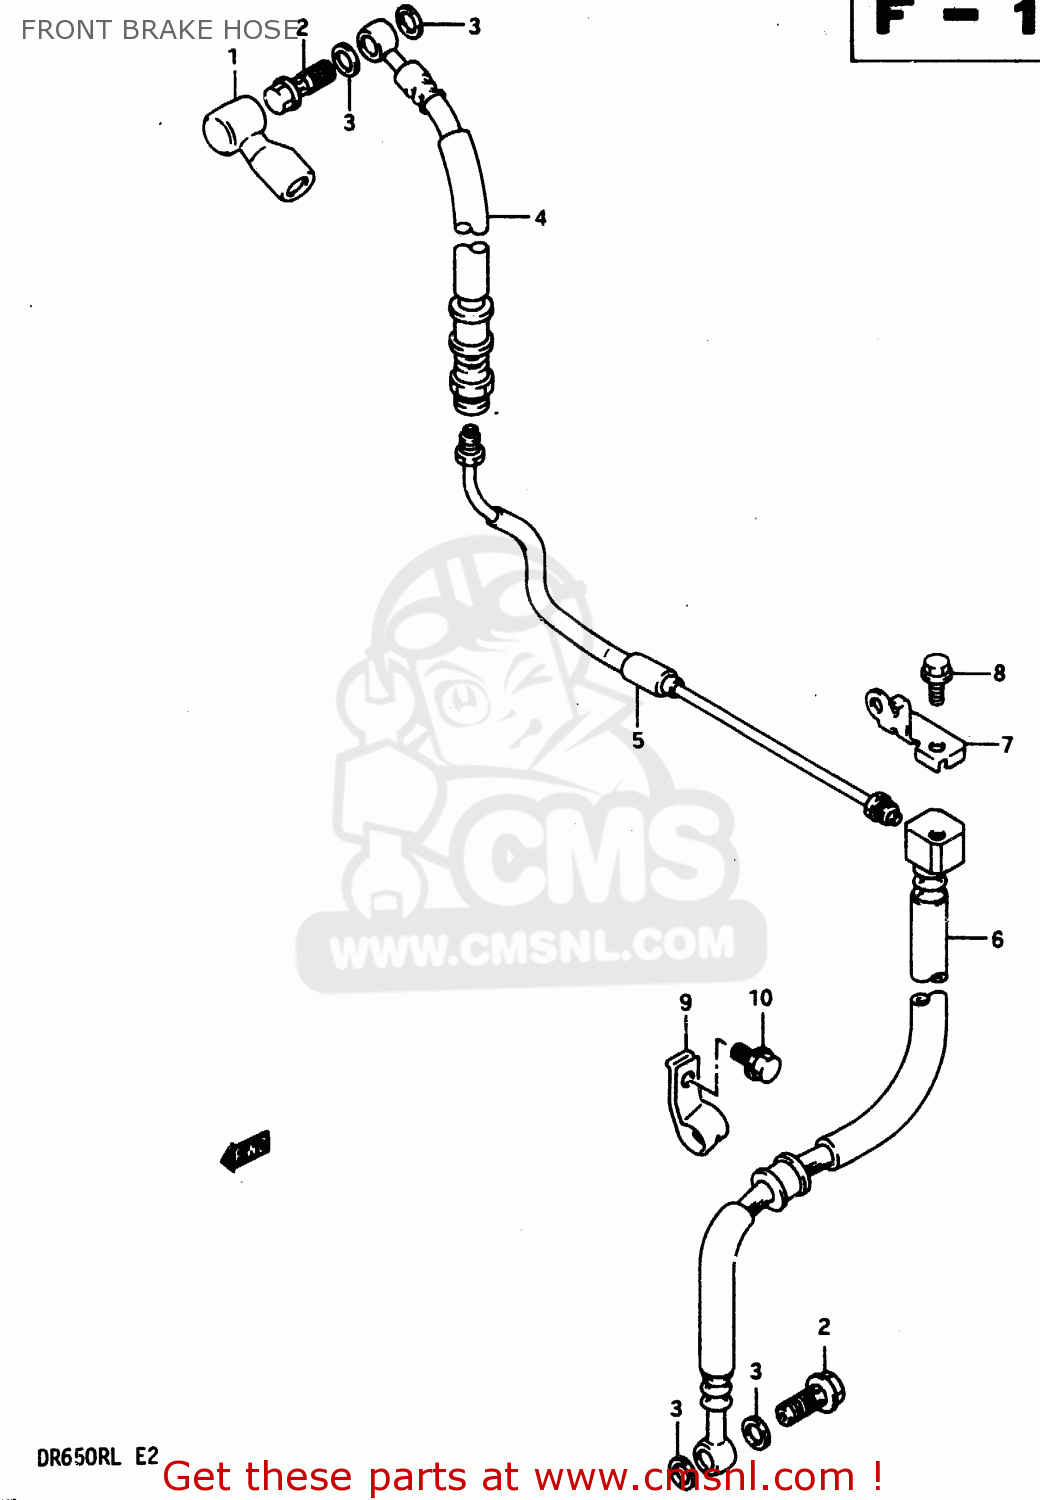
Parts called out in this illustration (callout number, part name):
1	BOOT,MASTER CYLINDER
2	BOLT UNION
3	WASHER(10X15X1.5)
4	HOSE COMP,FRONT BRAKE
5	PIPE COMP,FRONT BRAKE
6	HOSE COMP,FRONT BRAKE
7	BRACKET,FRONT BRAKE HOSE
8	BOLT
9	CLAMP,FR BRAKE HOSE NO.2
10	BOLT
